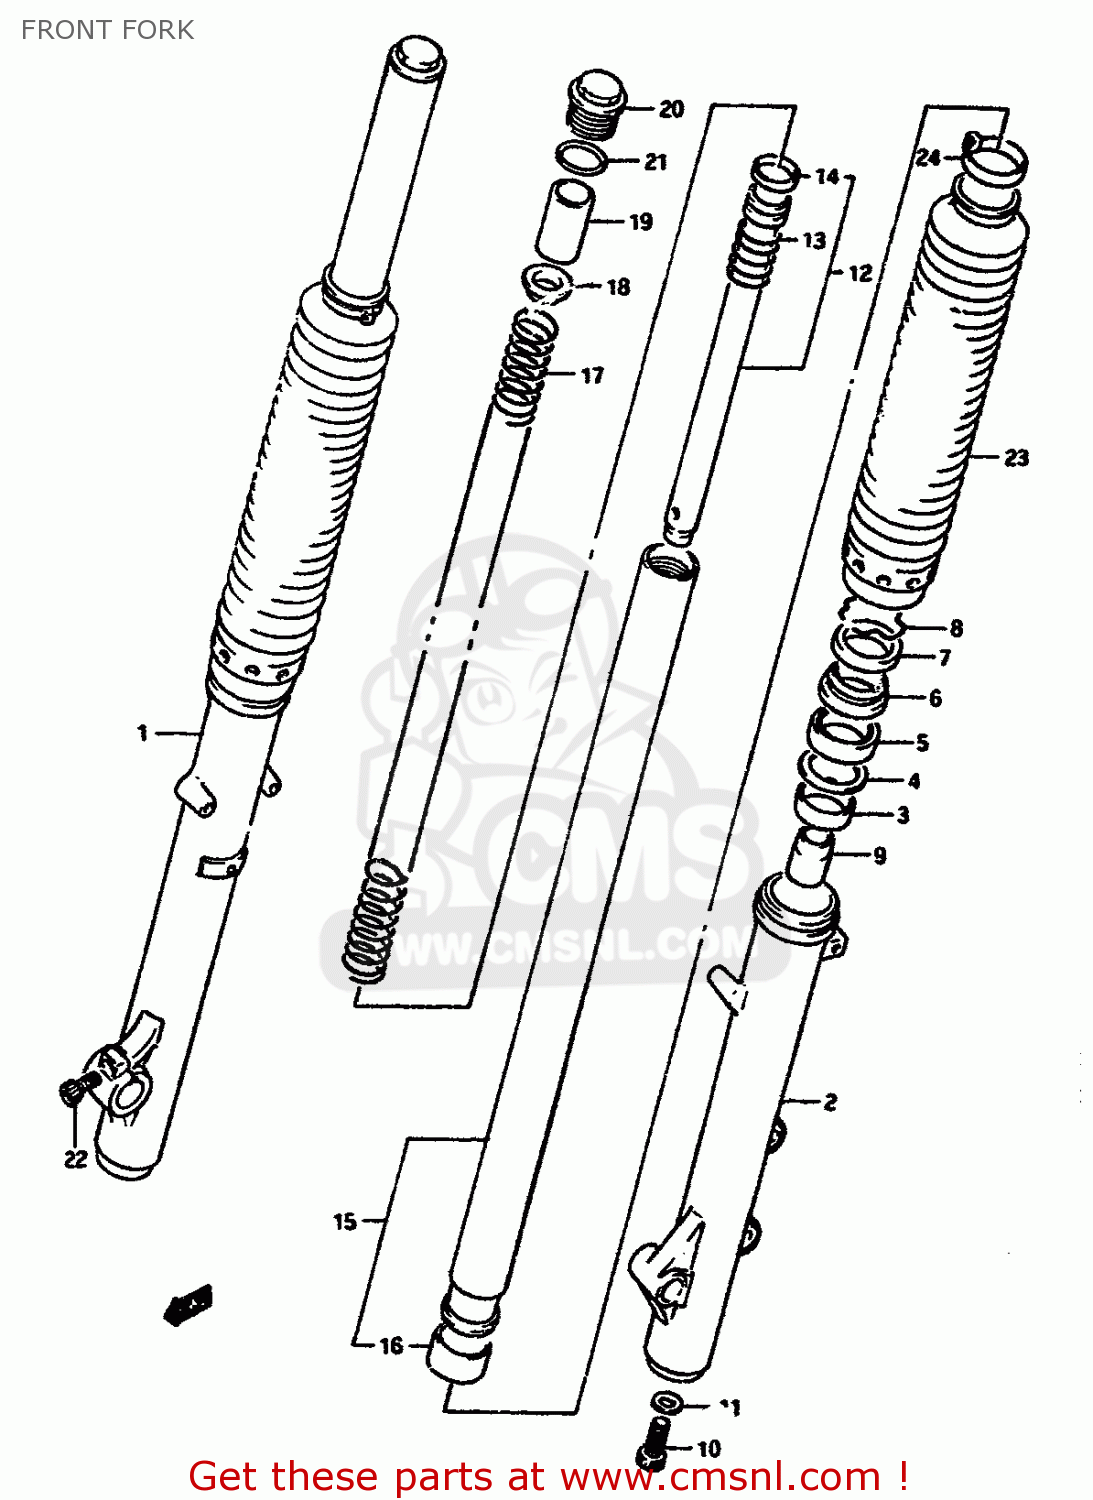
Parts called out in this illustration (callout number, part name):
1	TUBE,OUTER,RIGHT
2	TUBE,OUTER,LEFT
3	METAL,SLIDE
4	WASHER,FORK OIL SEAL
5	SEAL,OIL
6	SEAL,DUST
7	WASHER
8	RING,OIL SEAL STOPPER
9	PIECE,OIL LOCK
10	BOLT(14X25)
11	GASKET (NAS)
12	CYLINDER
13	SPRING,REBOUND
14	RING,FR FORK PISTON
15	TUBE,INNER
16	PISTON
17	SPRING
18	GUIDE,SPRING
19	SPACER,SPRING
20	CAP,FORK
21	O-RING
22	BOLT,SOCKET HEAD(8X22)
23	BOOT
24	BAND,BOOT
